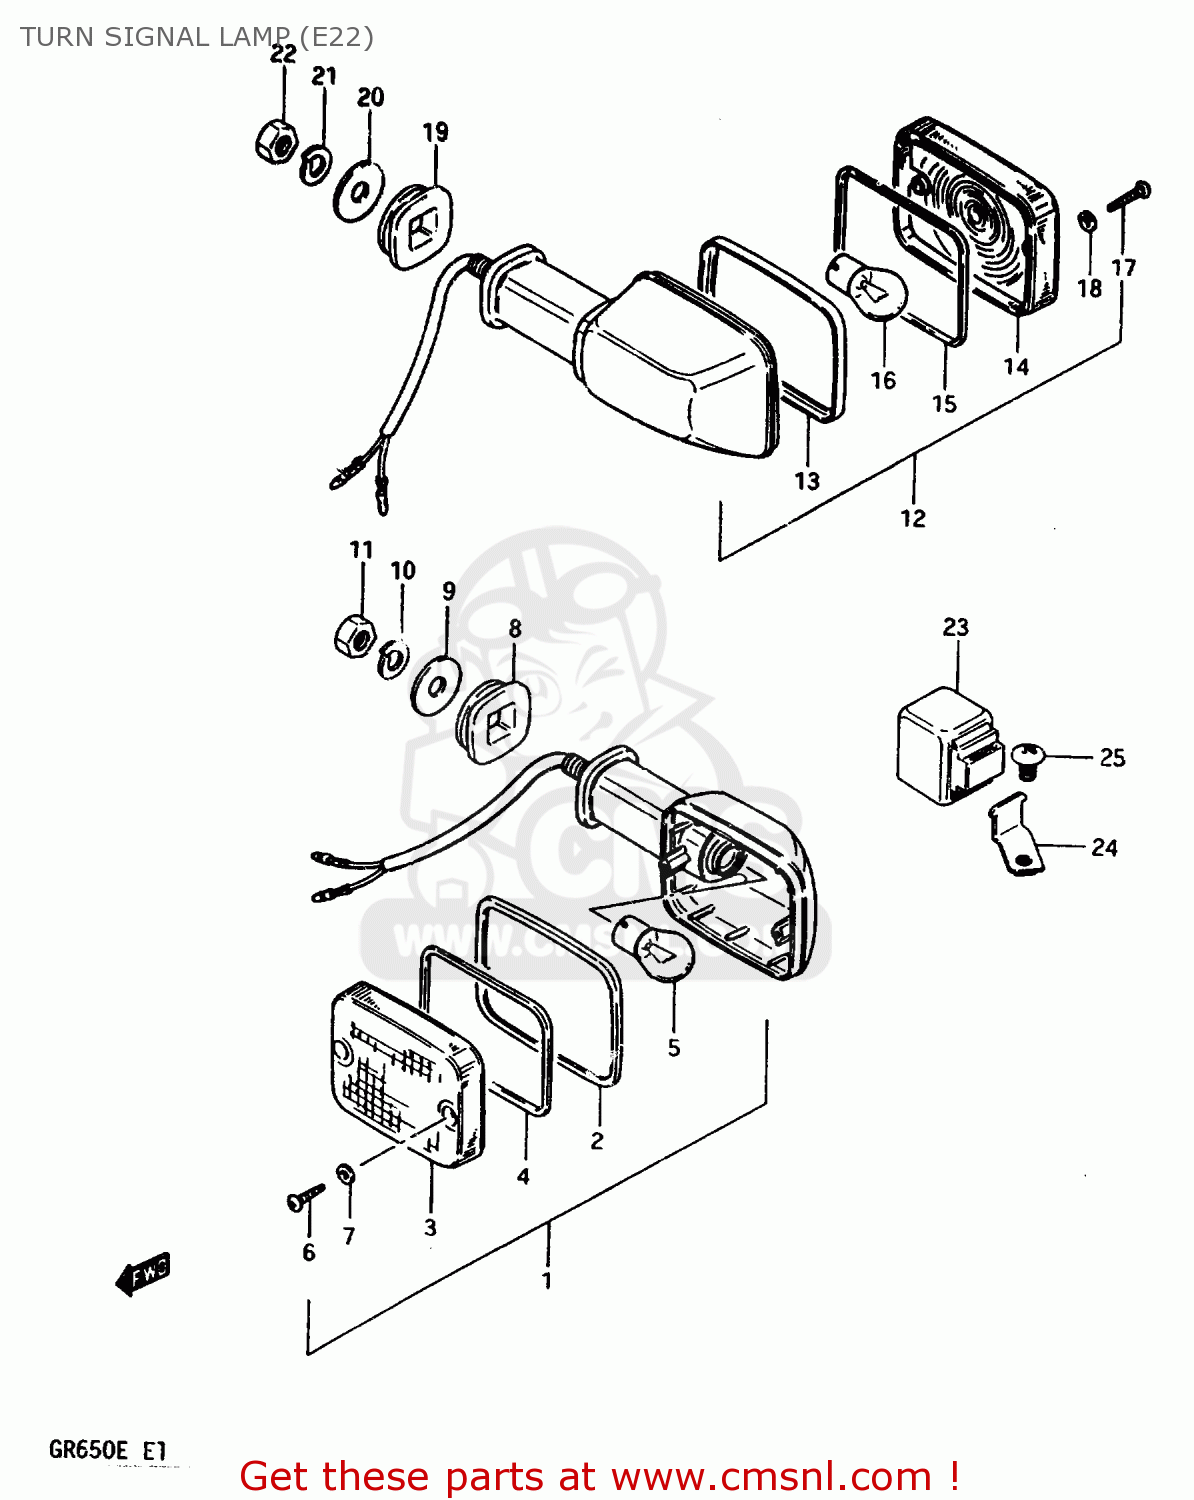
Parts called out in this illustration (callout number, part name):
1	LAMP ASSY, FRONT TURN SIGNAL
2	RIM
3	LENS
4	GASKET (NAS)
5	BULB(12V21W)
6	SCREW
7	GASKET (NAS)
8	CUSHION
9	WASHER (10.5X30X2.3)
10	LOCK WASHER
11	NUT
12	LAMP, REAR TURN SIGNAL
13	RIM
14	LENS
15	GASKET (NAS)
16	BULB(12V21W)
17	SCREW
18	GASKET (NAS)
19	CUSHION
20	WASHER (10.5X30X2.3)
21	LOCK WASHER
22	NUT
23	RELAY, TURN SIGNAL
24	BRACKET,TURN SIGNAL RELAY
25	SCREW
